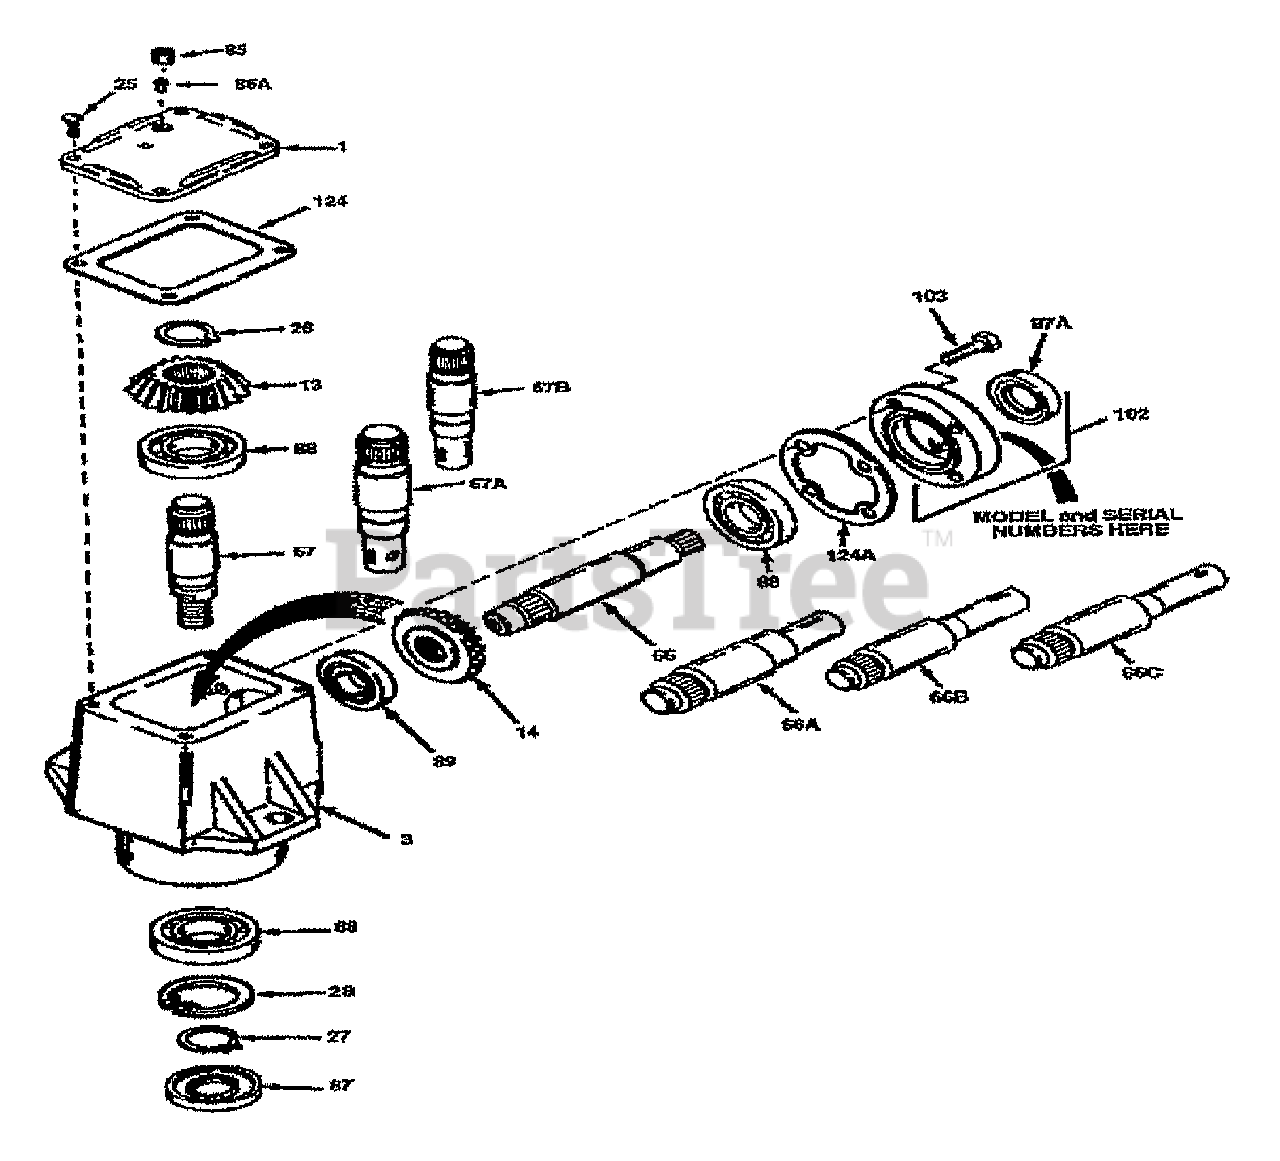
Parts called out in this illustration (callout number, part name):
13	MITER GEAR
26	RET RING
26A	LOAD RING
27	RET RING
66A	INPUT SHAFT
67A	OUTPUT SHAFT
87A	OIL SEAL
88	BALL BEARING
89	BALL BEARING
102	CAP & SEAL
124	GASKET
124A	GASKET
